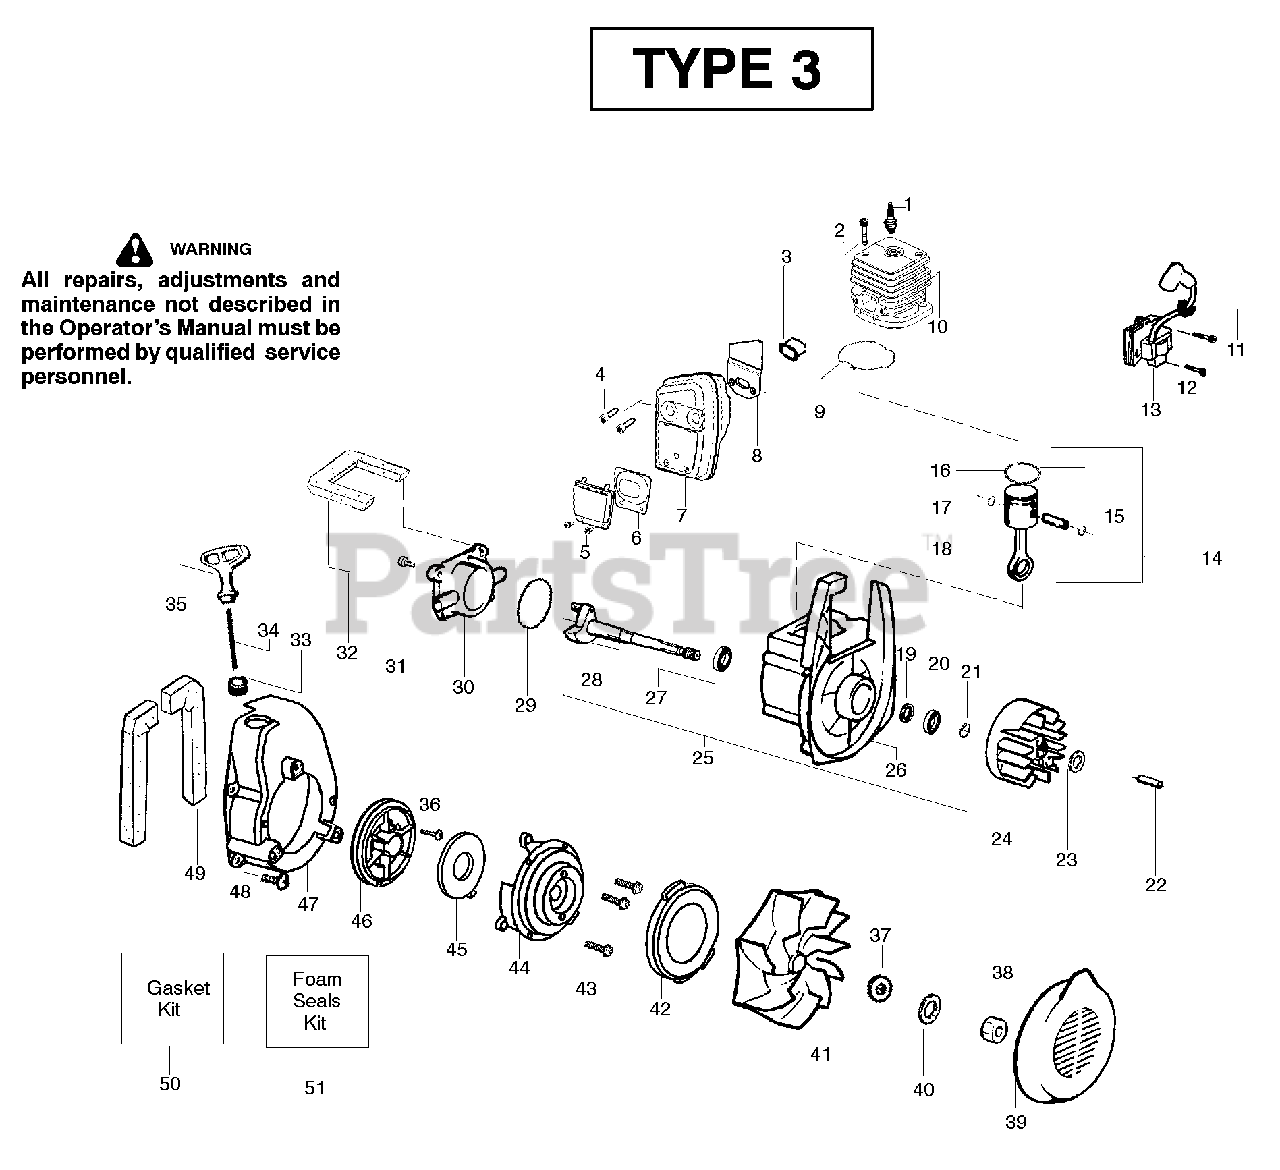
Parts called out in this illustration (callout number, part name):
1	Spark Plug (RCJ-6Y)
3	Insulator-Heat
4	Screw-Muffler-Internal
6	Kit-Spark Screen
7	Kit-Muffler
8	Gasket-Baffle (kit)
9	Gasket-Cylinder (kit)
10	Kit-Cylinder
11	Grommet-Ign. Module
12	Screw-Ignition Module
13	Ignition Module
14	Kit-Piston/Rod
15	Kit-Piston
16	Piston Ring
17	Retainer-Piston Pin
18	Assy-Connecting Rod
20	Bearing-Outer
21	Retainer Ring-C'chaft
22	Spacer-Flywheel
24	Assy-Flywheel
25	Assy-Crankcase/Crank shaft
26	Assy-Crankcase
27	Bearing-Inner
28	Assy-Crankshaft
29	O-ring-C/case (kit)
30	Cover-Crankcase
31	Screw
32	Foam-219mm (kit)
33	Eyelet-Flange
34	Kit-Rope
35	Handle-Starter
36	Screw-Rope
37	Washer-Belleville
39	Inlet Door
41	Kit-Impeller Assy.
42	Seal-Ring
44	Housing-Pulley
45	Spring-Starter
46	Kit-Starter Pulley
47	Fan Housing
48	Screw
49	Foam-182mm (kit)
50	Kit-Gasket
51	Kit-Foam Seals
